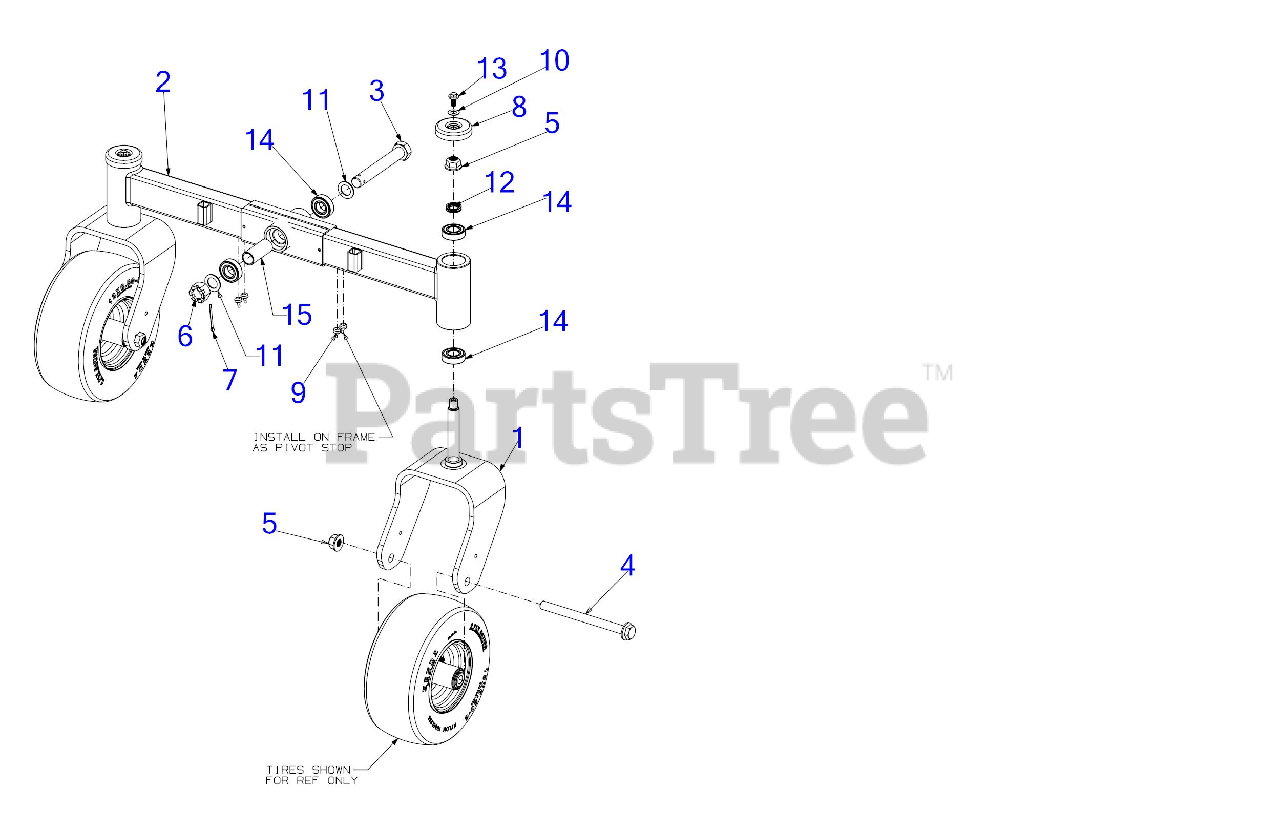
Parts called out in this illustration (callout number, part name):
3	HEX HEAD SCREW 1-14 X 7 GR5
4	SCREW 3/4-16 x 9.00 GR5
5	FLANGE LOCK NUT 3/4-16 TOP LOCK
6	CASTLE NUT 1.0-14 GR5
7	COTTER PIN
8	AXLE CAP 3"
9	BUMPER, .62 DIA x .3
10	BELL WASHER
11	FLAT WASHER 1.031 X1.62 X.095
12	WAVE WASHER
14	BALL BEARING 1.0 X 52 X 15
15	SPACER 1.00 X 1.25 X 2.99
